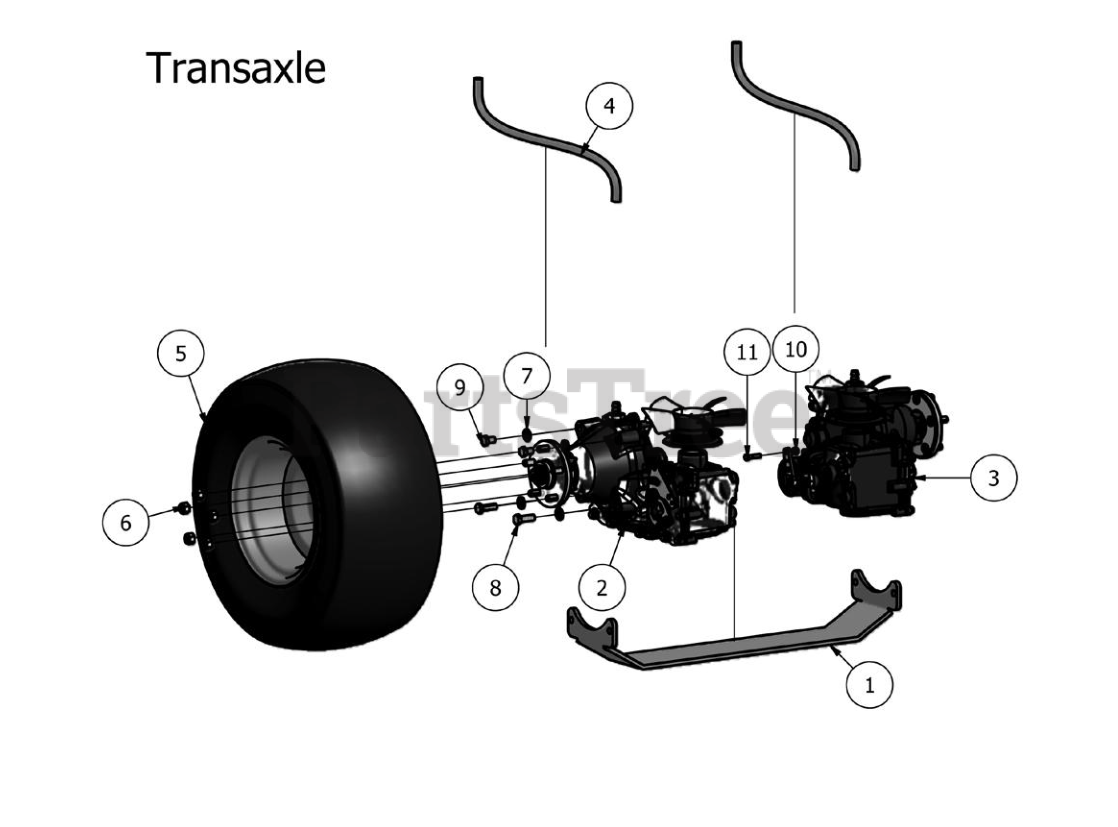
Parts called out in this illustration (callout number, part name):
1	Outlaw TransAxle Cross Brace
2	ZT-5400 Left
3	ZT-5400 - Right
4	1/2 Clear Braided Hose PRICED PER FOOT
5	24 x 12 x 10 Tire and Wheel
6	Acorn Lug Nut
7	1/2 Lock Washer Zinc
8	1/2-20 x 1-1/2 Grade 5 Hex Bolt Zinc
9	1/2 x 3/4 Bolt
10	5/16-18 Nylon Insert Locknut Zinc Orange Nylon
11	5/16-18 x 1-1/4 Grade 5 Hex Bolt
